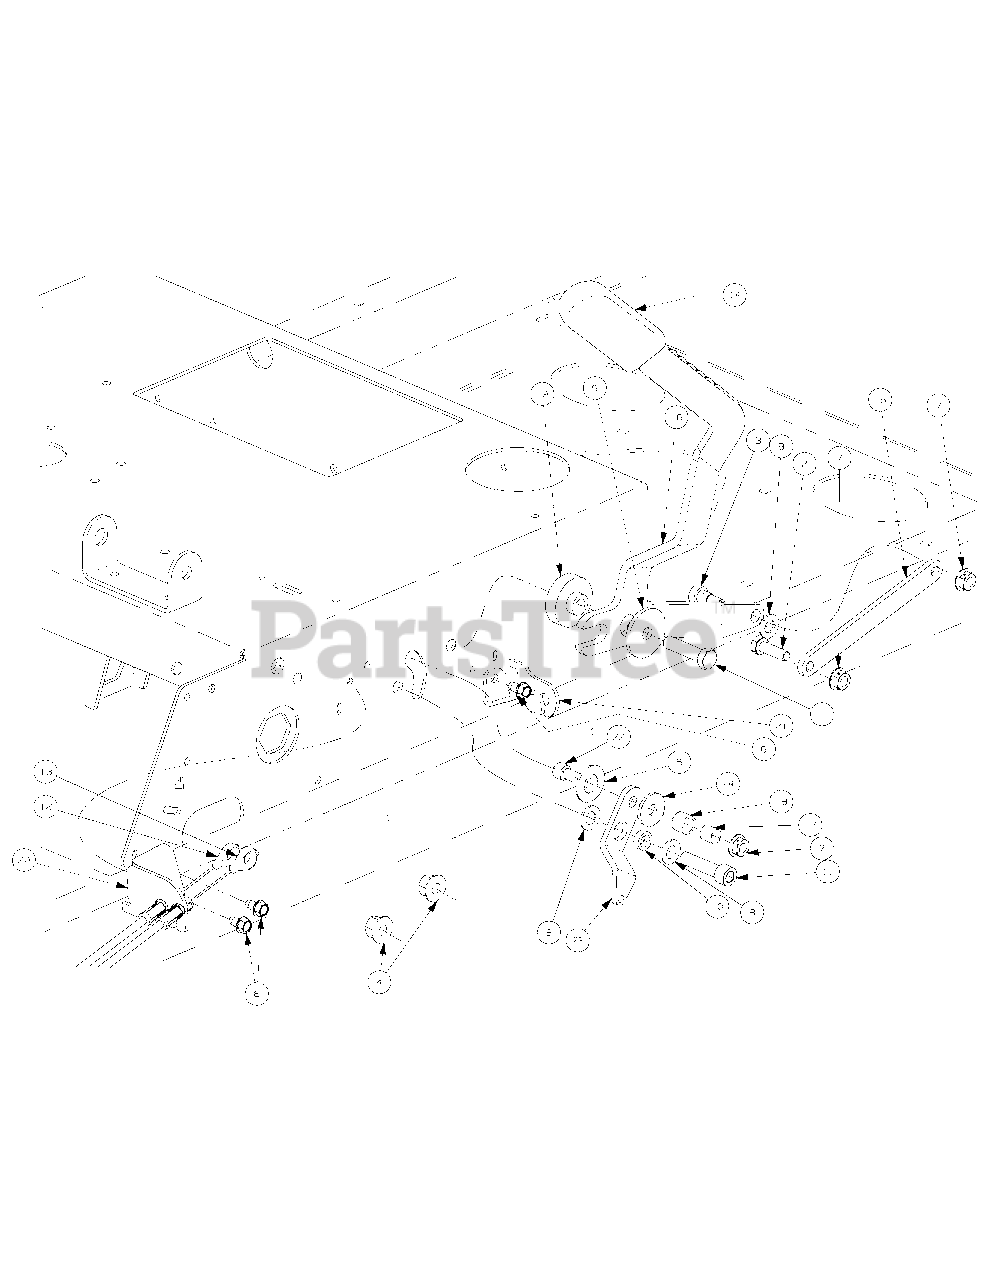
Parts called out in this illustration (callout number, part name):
1	Hex Head Cap Screw, 3/8-16 x 1.50
2	Hex Head Cap Screw, 5/16-18 x 1.00
3	Shoulder Bolt, 3/8 x 3/8
4	Hex Nut, 3/8-16 Flange Lock
5	Slide Washer
6	Screw, TT, 1/4-20, 0.5, Hex Index Washer
7	Nut, 5/16-18, Flange Lock
8	Washer, .375 x .738 x .063
9	Flat Washer, .390 x 1.5 x .134
10	Spacer, .380 x .563 x .196
11	Sockethead Capscrew, 3/8-16 x 1.50
12	Left Hand Brake Cable
13	Right Hand Brake Cable
14	Parking Brake Grip
15	Brake Link Plate
16	Brake Handle
17	Spacer, .322 ID x .438 OD x .44
18	Spacer, .442 ID x .563 OD x .405
19	Step Hub, .379 x 1.5 x .257/.400
20	Brake Cable Mounting Bracket
21	Brake Cable Mounting Bracket
22	Sockethead Capscrew, 5/16-18 x 1.00
23	Lockout Lever Plate
24	Washer, .345 x 1.00 x .100
